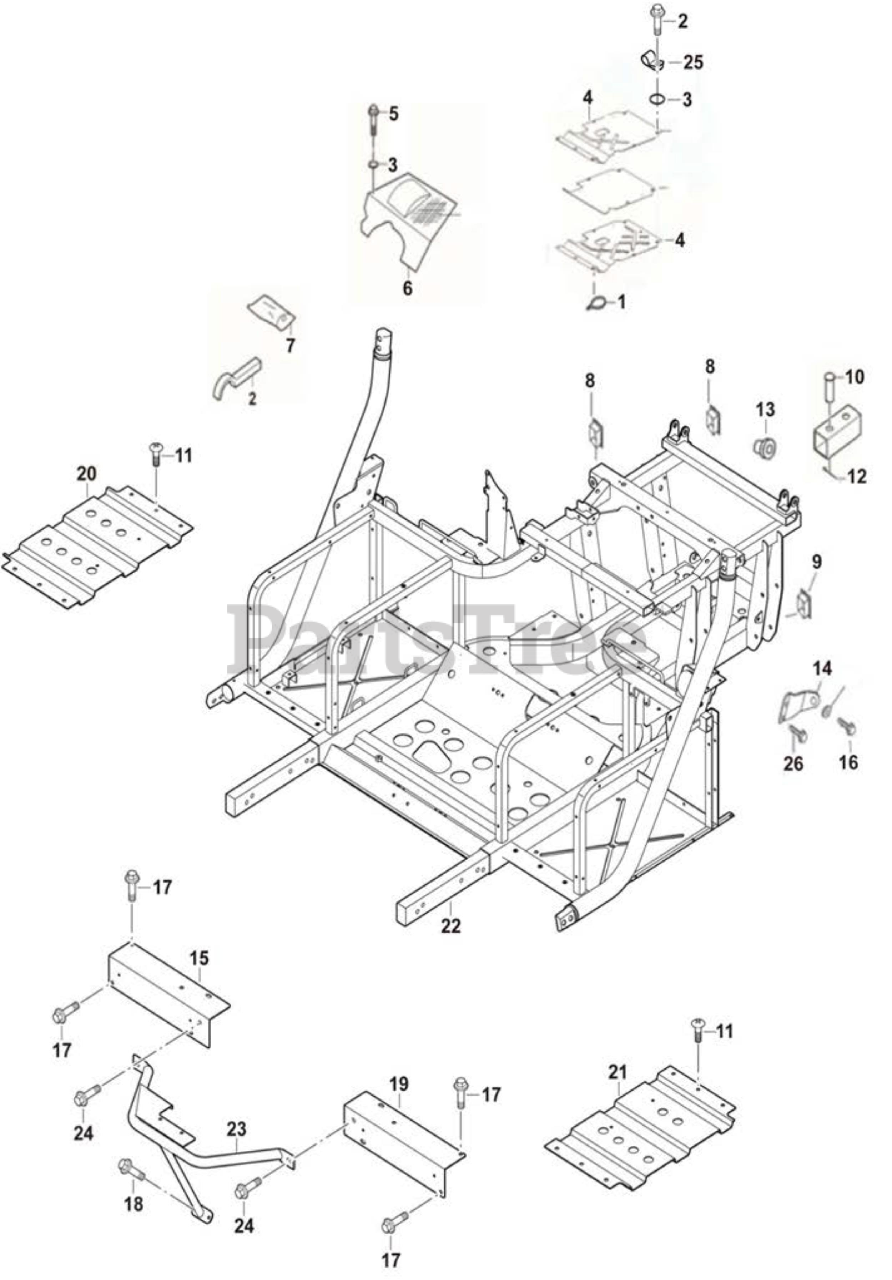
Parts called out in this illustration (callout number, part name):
1	Water Pipe Clip V
2	Hexagon Flange Bolt M6X16
3	Flat washer 6
4	Cargo Box Insulation Plate
5	Cross Large Plate Head Screw M6X12
6	Thermal baffle,muffler
7	basic hand tool
8	Rectangle Plastic Plug 25X40
9	Rubber Block 40X60
10	Step Cotter Pin 23X86
11	Cross Large Plate Head Screw M8X16
13	Shock Pad,circular plug 10X27
14	Rear Axle Upper Mounting Plate I
15	Seat Support Plate II
16	Hexagon Flange Bolt M10X1.25X25
17	Hexagon Flange Bolt M8X16
18	Hexagon Flange Bolt M6X16
19	Seat Support Plate I
20	Supporting Plate, Rear Right
21	Supporting Plate, Rear Left
22	back-end assy, Frame
23	Mounting Bracket, Air Filter
24	Hexagon Flange bolt M10X1.25X25
25	Wire Clamp
26	Hexagon Flange Bolt M8X20
